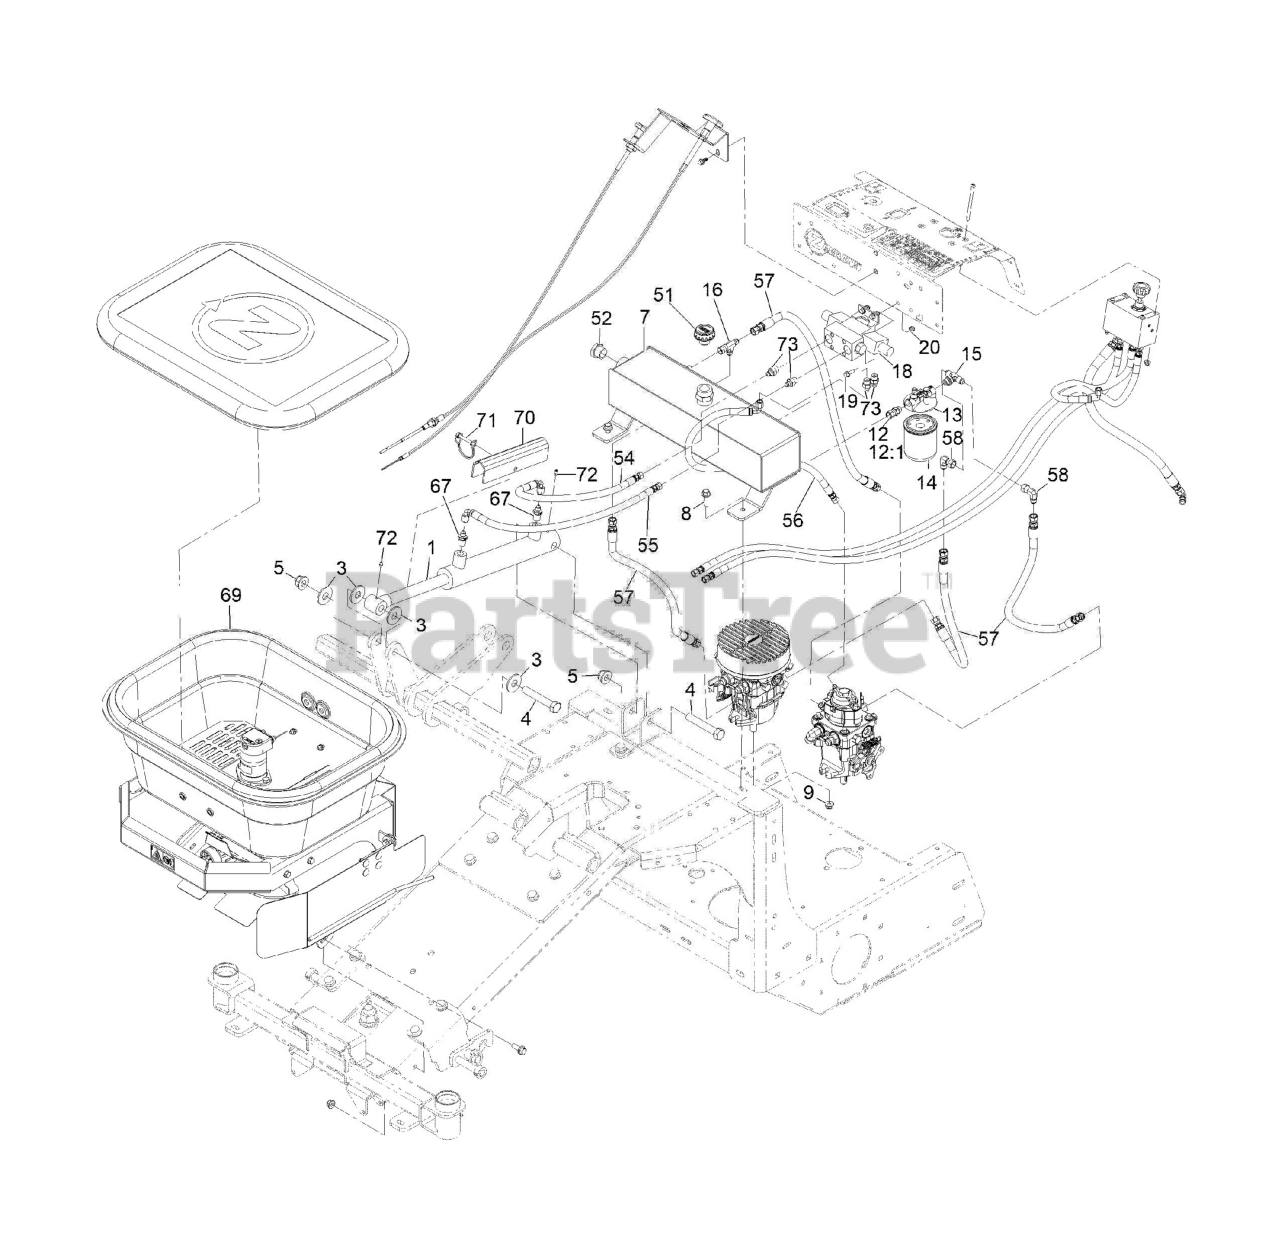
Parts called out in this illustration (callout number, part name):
1	LIFT CYLINDER NEW STYLE 8
3	WASHER-FLAT
4	SCREW-HH
5	Nut-Hex Flg 5/8-11 Nyloc
7	TANK-HYDRAULIC, ZPLUG
8	SCREW-HHF
9	NUT-HF, NI
12	6FJIC SWIVEL-6MORB
12:1	O-RING
13	HEAD-FILTER
14	Filter-Hydraulic
15	TEE-6MJIC-6MJIC-6MORB
16	FITTING-HYD, TEE
18	PARKER ELECTRIC ACTUATED
19	SCREW-HHF
51	HYDRAULIC TANK VENT CAP
52	FLUID SITE WINDOW
54	Hose ASM-HYD HP
55	Hose ASM-HYD HP
56	Hose ASM-HYD HP
57	HOSE-24,3/8,100R6,6FJIC,6
58	ELBOW-SWIVEL, 90 DEG
67	FITTING-STR
70	STOP-CYLINDER
71	PIN-HITCH
72	FITTING-GREASE
